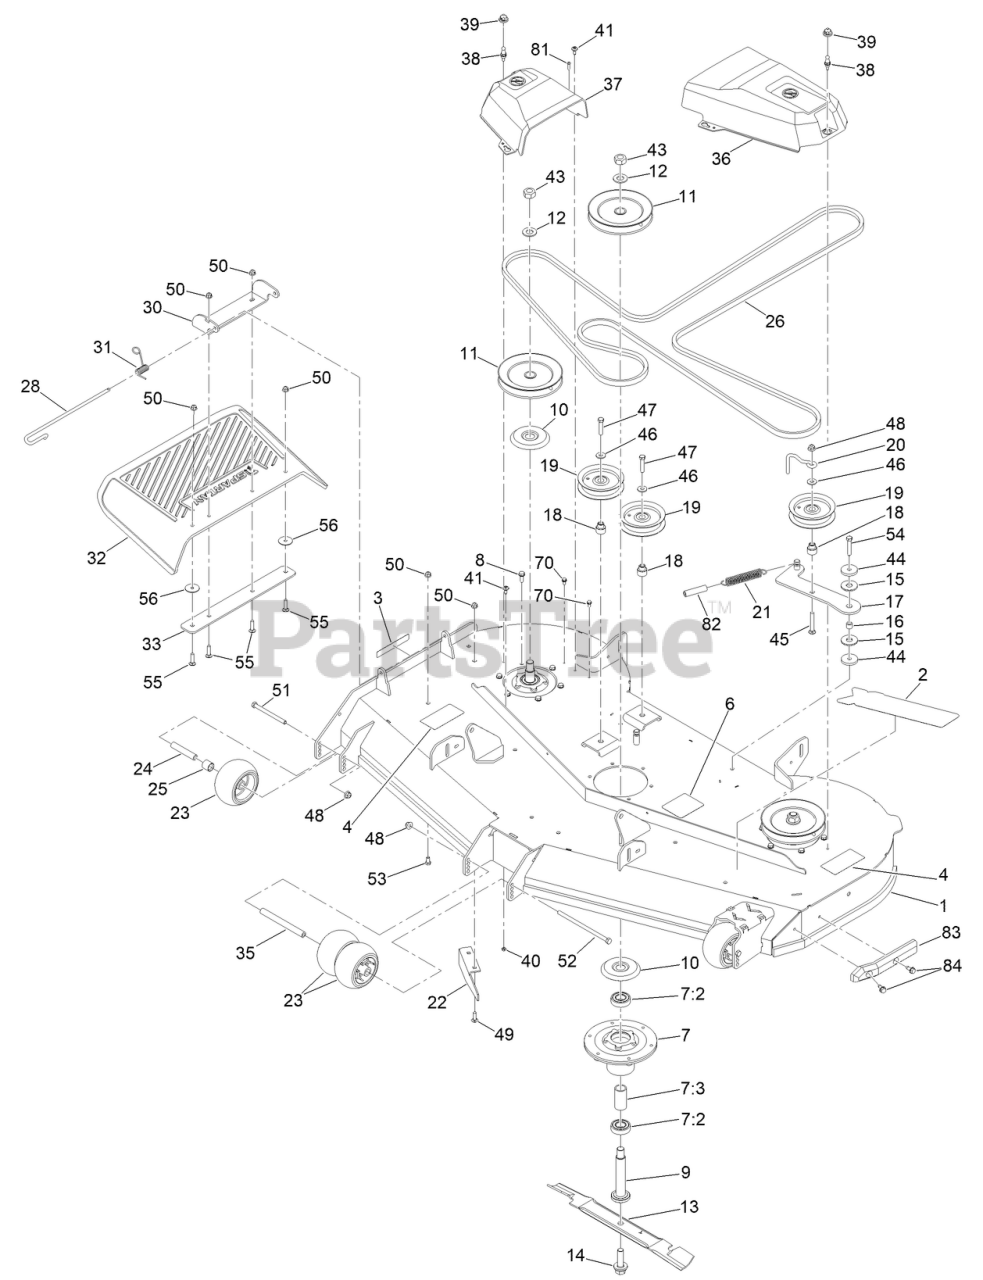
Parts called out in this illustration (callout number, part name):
1	60 IN DECK DECAL ASM
2	DECAL-XTF
3	DECAL-DANGER
4	DECAL-DANGER, DECK
6	DECAL-ROUTING, BELT
7	SPINDLE ASM
7:2	BEARING-BALL
7:3	SPACER-BEARING
8	SCREW-TAPTITE
9	SHAFT-SPINDLE
10	SHIELD-BEARING
11	PULLEY
12	WASHER
13	BLADE-HI FLOW, 20.5 INCH
14	SCREW-BLADE
15	WASHER-FRICTION, COMPOSITE
16	SPACER
17	IDLER ARM ASM
18	BUSHING-IDLER
19	PULLEY-IDLER, FLAT
20	GUIDE-BELT, IDLER
21	SPRING-EXTENSION
22	BAFFLE-CUTOFF
23	ROLLER-SCALP, ANTI
24	TUBE-SPANNER
25	SPACER-AXLE, REAR
26	BELT-V
28	PIN-CHUTE
30	BRACKET-DEFLECTOR, UPPER
31	SPRING-TORSION
32	DEFLECTOR-DISCHARGE
33	PLATE-DEFLECTOR
35	SPACER-WHEEL
36	COVER-BELT, LH
37	COVER-BELT, RH
38	STUD-BALL
39	GROMMET-BALL
40	NUT-LOCK
41	SCREW-SHOULDER
43	NUT-HEX
44	WASHER-PLAIN
45	SCREW-CARR
46	WASHER-HARDENED
47	SCREW-HH
48	NUT-HF, NI
49	SCREW-CARR
50	NUT-HF, NI
51	SCREW-HH
52	SCREW-HH
53	SCREW-HH
54	SCREW-HH
55	SCREW-CARR
56	WASHER-FLAT
70	SCREW-HWH
81	RIVET-TRIFOLD
82	HOSE-BREATHER
83	BUMPER-DECK
84	SCREW-HWHTF
